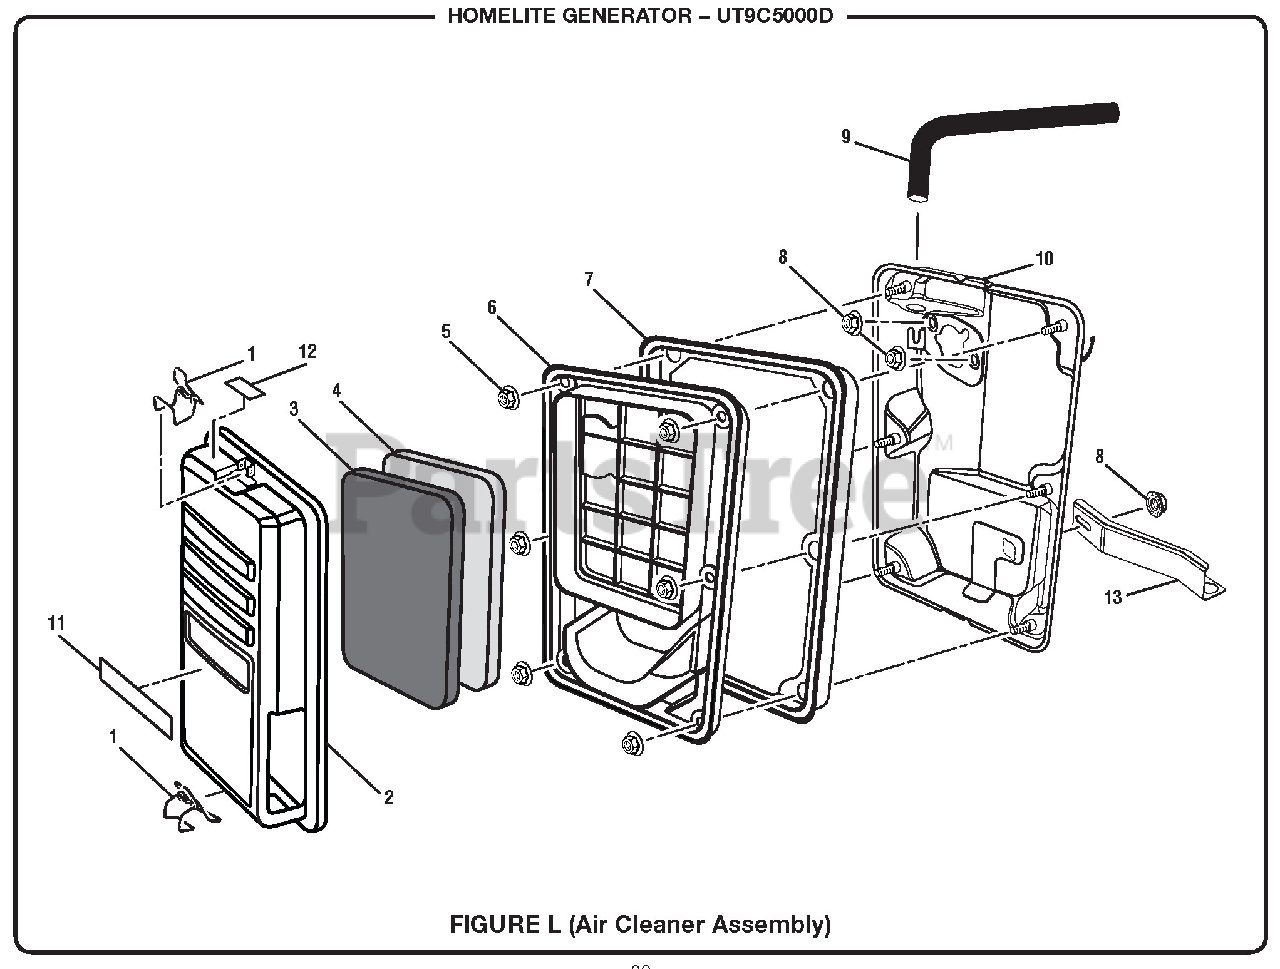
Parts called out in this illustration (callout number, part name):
1	Air Cleaner Cover Hinge
2	Air Cleaner Cover Assembly
3	Pre-filter
4	Air Filter Element
5	Nut (M5, Flange Nut)
6	Filter Element Retainer
7	Air Cleaner Gasket
8	Nut (M6, Flange Nut)
9	Breather Tube
10	Air Cleaner Support
11	Starting Instruction Label
12	Choke Label
13	Air Cleaner Bracket
